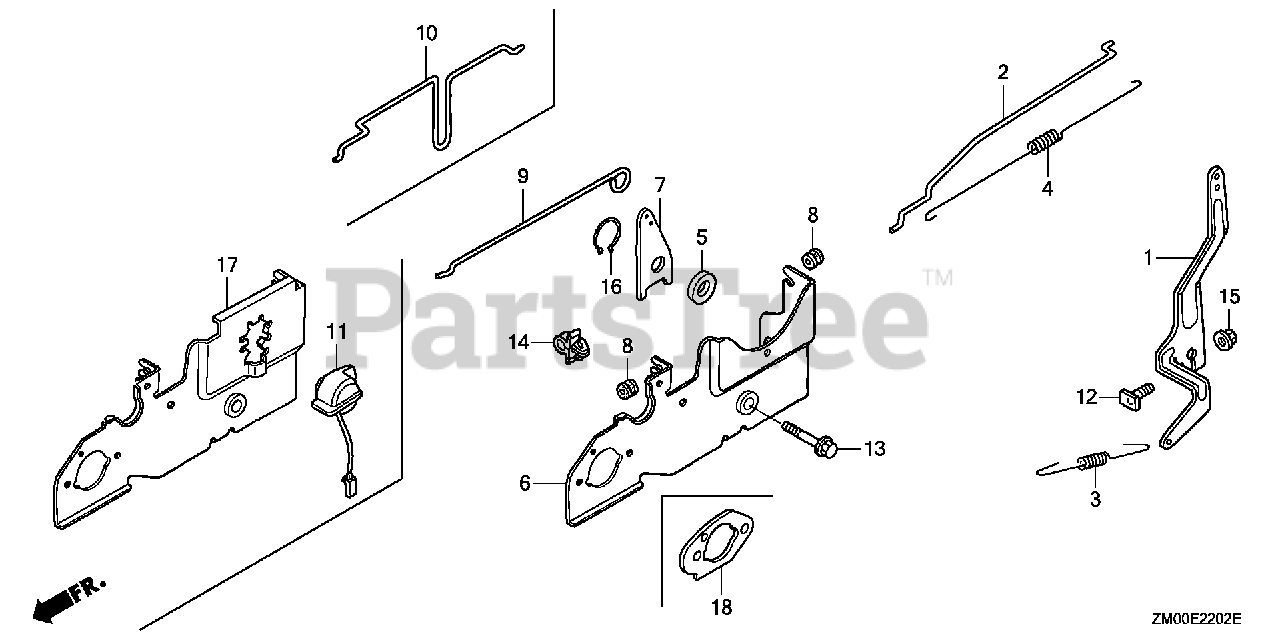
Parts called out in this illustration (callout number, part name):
1	ARM, GOVERNOR
2	ROD, GOVERNOR
3	SPRING, GOVERNOR
4	SPRING, THROTTLE RETURN
12	BOLT, GOVERNOR ARM
14	HOLDER, WIRE (FASTEX)
15	NUT, FLANGE (6MM)
18	SPACER, CARBURETOR
